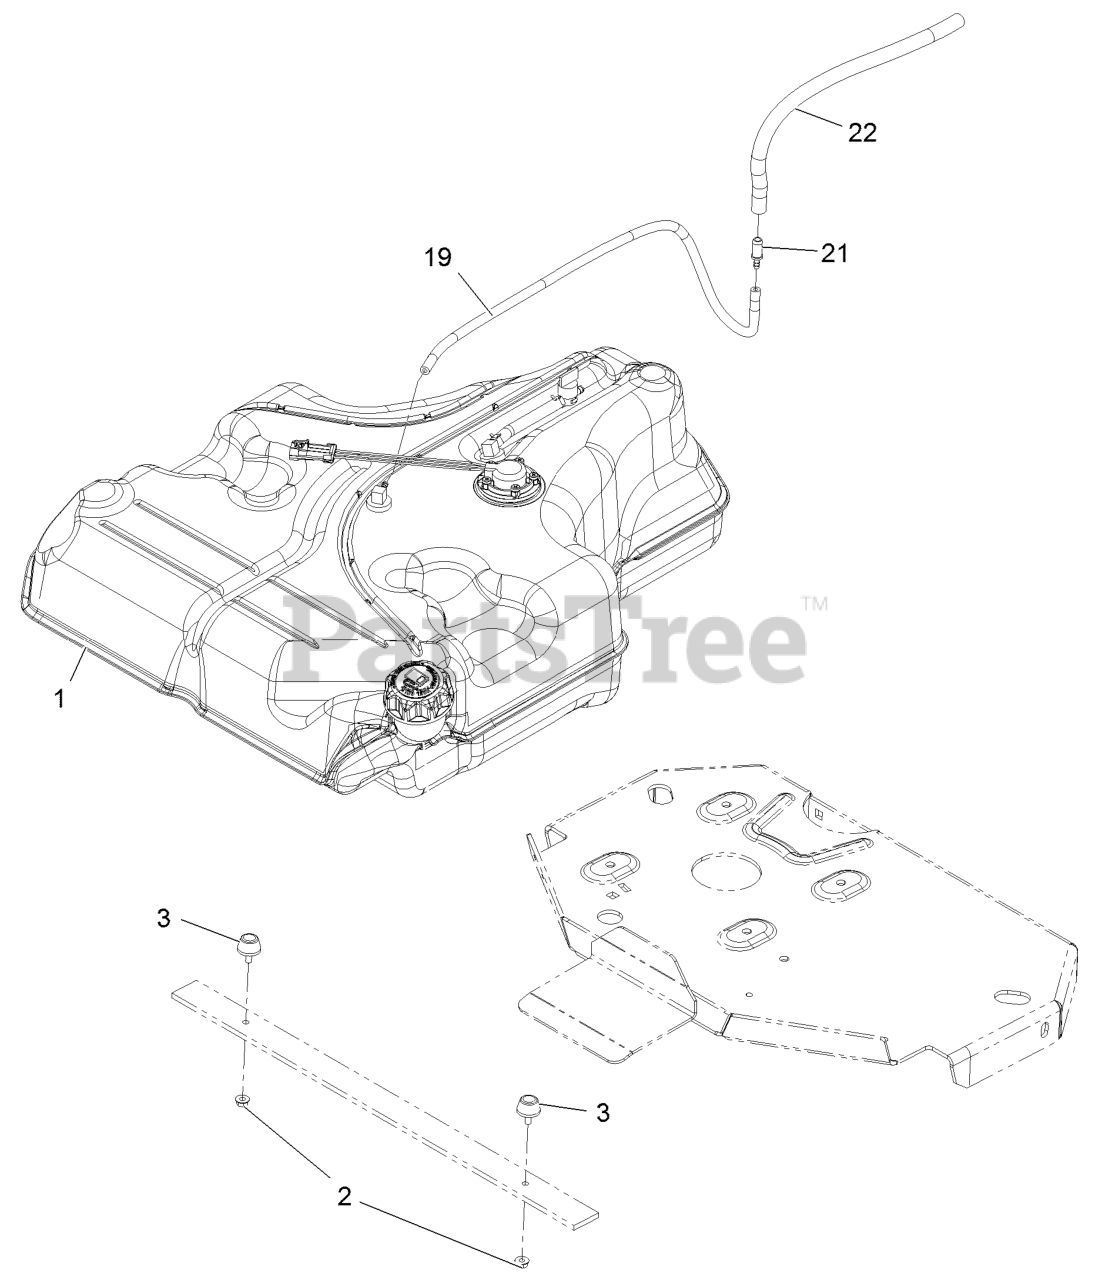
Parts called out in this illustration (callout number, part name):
2	NUT-JAM
19	HOSE-FUEL
21	FITTING-STRAIGHT
22	HOSE-FUEL
